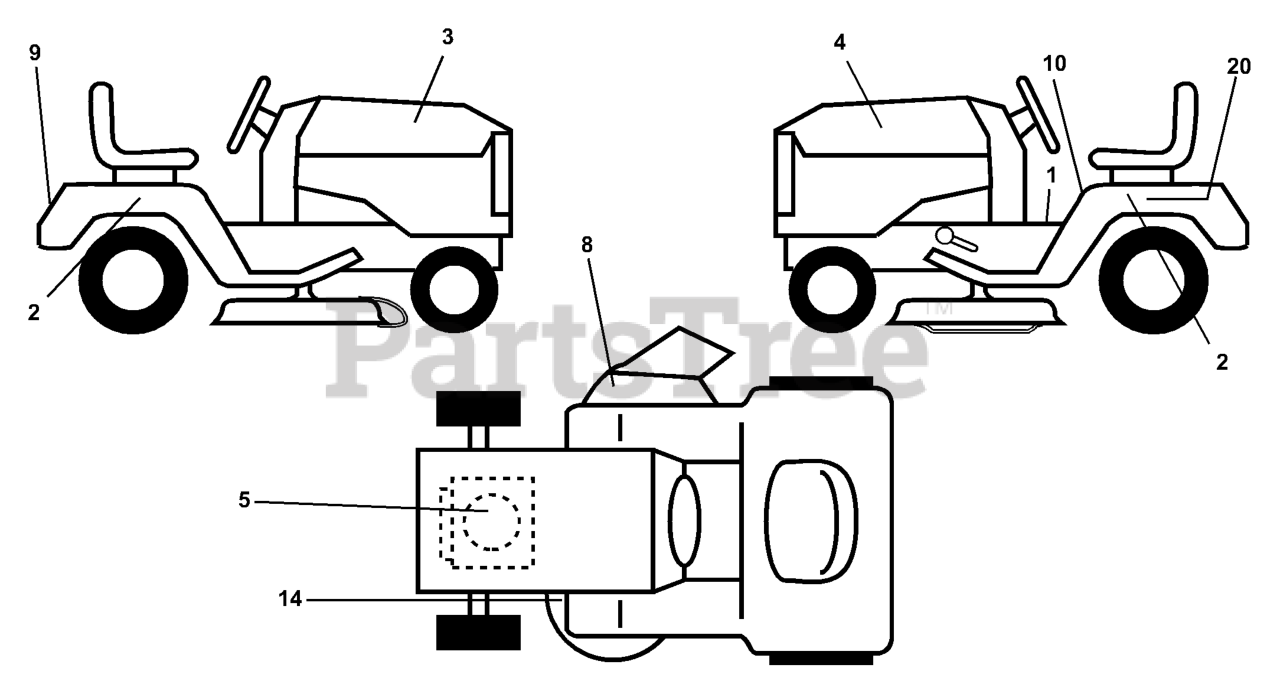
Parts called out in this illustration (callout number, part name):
3	DECAL HOOD RH
4	DECAL HOOD LH
5	DECAL HP ENGINE
8	DECAL WARNING (ENGLISH/FRENCH)
9	DECAL FENDER HUSQ
10	DECAL FENDER DANGER
14	DECAL V BELT SCHEMATIC
20	DECAL BTRY SYMBOLS
